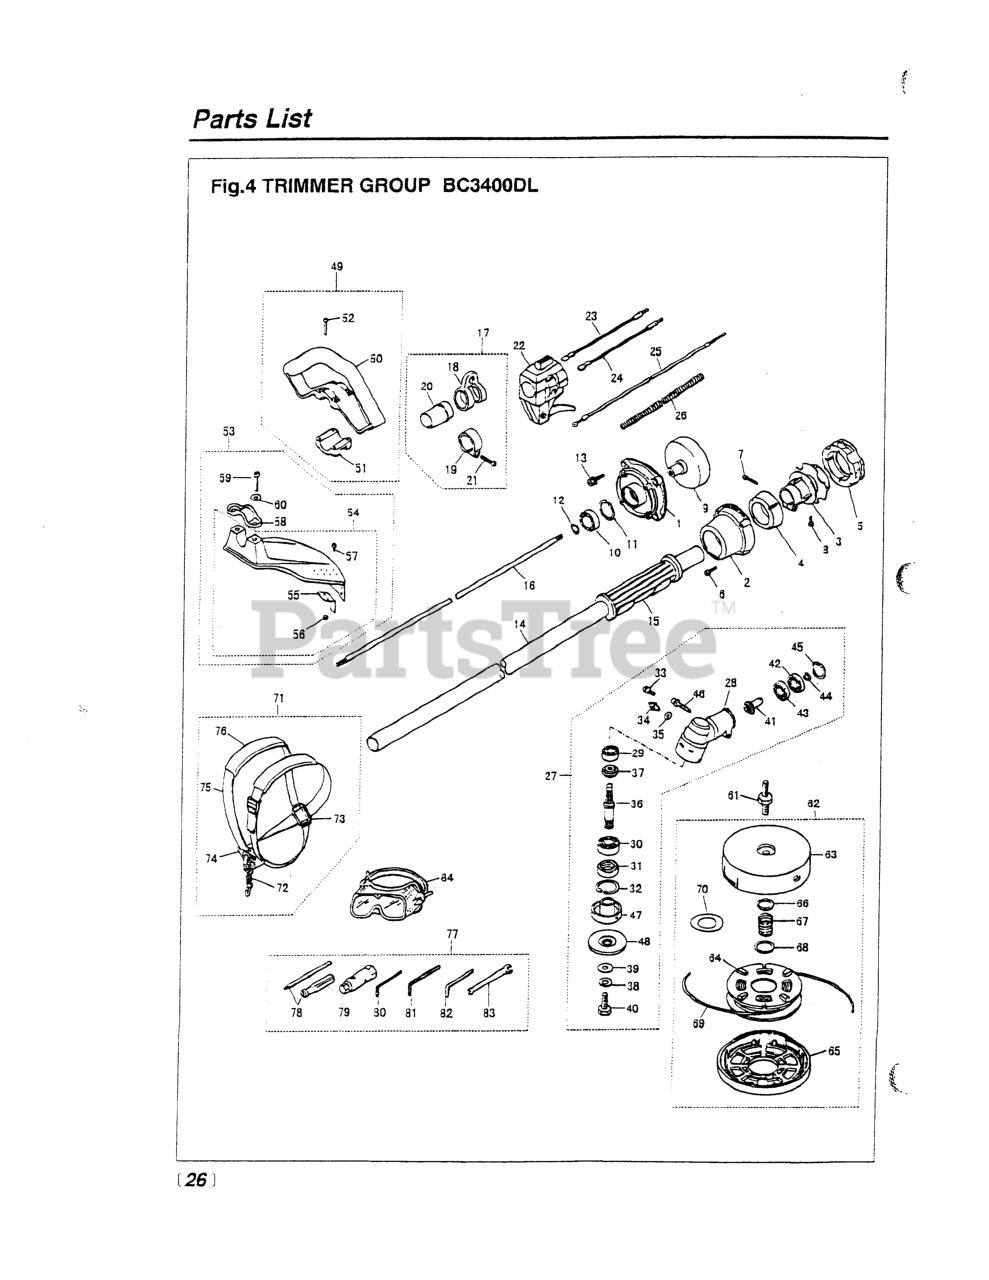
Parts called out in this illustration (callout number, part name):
1	HOUSING
2	CAP
3	JOINT
4	ABSORBER-F
5	ABSORBER-R
6	BOLT, M5 X 30
7	BOLT, M6 x 30
8	BOLT, M5 X 10
10	BEARING
11	RING, SNAP, M35 X 1.5
12	RING, SNAP, M15 X 1.0
13	BOLT, M6 x 20
14	PIPE COMP.
16	SHAFT, DRIVE (USE -12211)
17	HANGER ASSEMBLY
18	HANGER
19	CLAMP
21	SCREW, M5 x 25
23	CORD (A), BLACK
24	CORD (B), RED
25	CABLE COMP (RPLS 1633-83100)
26	TUBE
28	GEARCASE (RPLS -13113)
29	BEARING (RPLS T3403-13510)
31	SEAL, OIL
32	RING, SNAP, M32 x 1.2
33	BOLT, M5 X 10
34	FITTING, GREASE
35	WASHER, M6 X .8
36	SHAFT
37	GEAR, BEVEL
38	WASHER (RPLS 3180-13270)
39	WASHER, M8 x 2.3 (RPLS -20823)
40	BOLT, LH
41	PINION
43	BEARING (RPLS T3403-13510)
44	RING, SNAP
45	RING, SNAP, M26 X 1.2
46	BOLT, M6 x 1.35
47	HOLDER (A)
48	HOLDER (B)
49	HANDLE ASSEMBLY
50	HANDLE
51	CLAMP
52	SCREW, M5 x 35
53	GUARD ASSY (RPLS -24001)
54	GUARD COMP
55	BLADE
56	NUT
57	SCREW, M5 x 12
58	CLAMP
59	BOLT, M6 x 1.30
60	WASHER, M6 X 15
61	SHAFT (RPLS 3274-99120)
62	6
63	CASE (USE -99112)
65	COVER
66	PLATE, LARGE
68	PLATE, SMALL
69	CORD
70	SPACER
74	HANGER COMP.
75	BAND (NOT SOLD SEPARATELY)
76	PROTECTOR
77	TOOL SET
78	SCREWDRIVER
80	WRENCH (TOOL)
81	WRENCH (TOOL)
82	BAR
83	SPANNER, 8 X 10 (RPLS 2540- )
